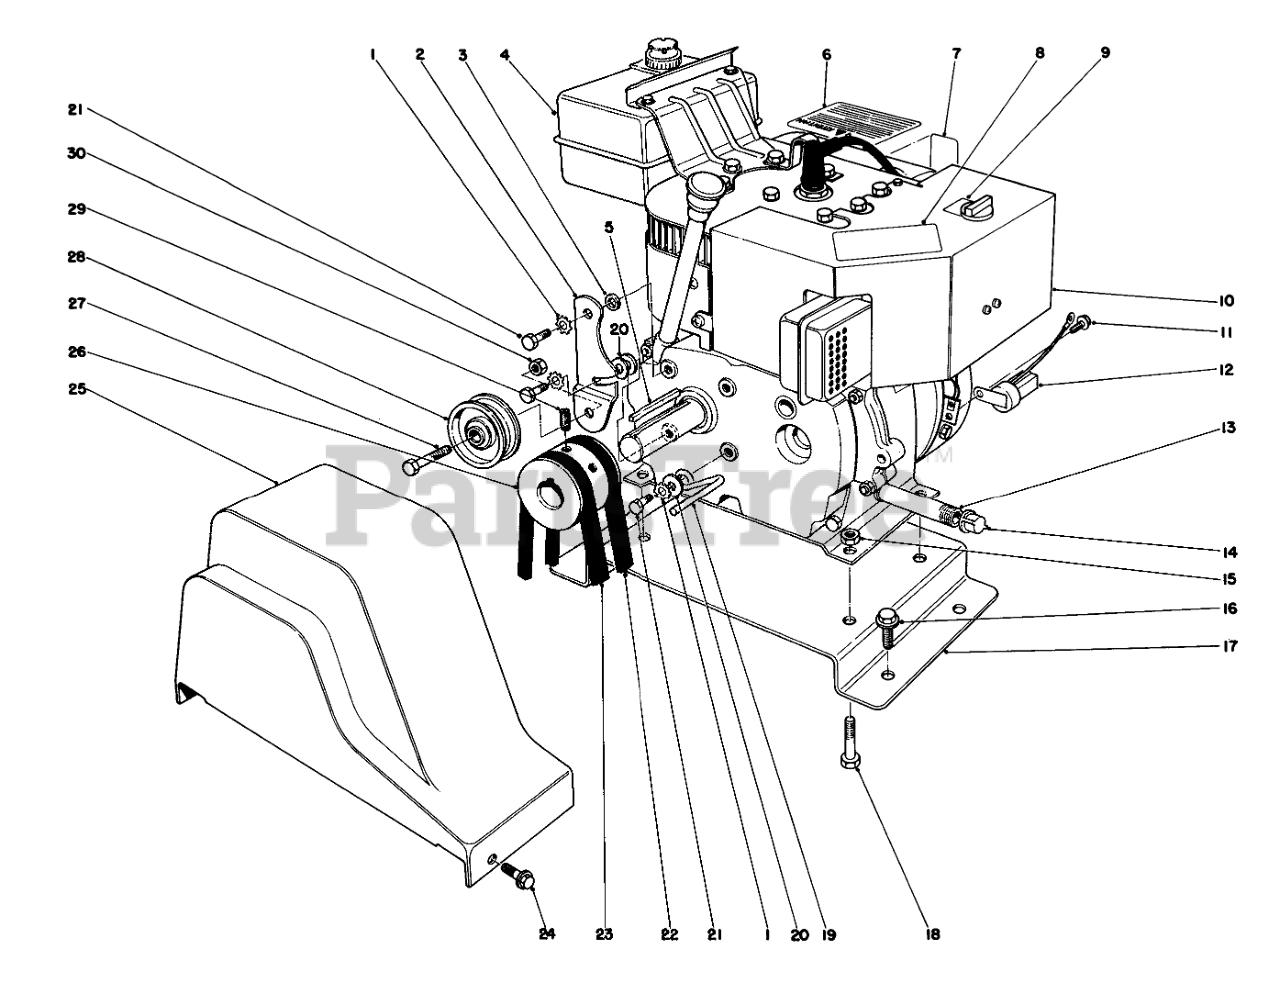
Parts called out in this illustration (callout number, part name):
1	WASHER-LOCK
2	ENGINE IDLER ARM
3	SPACER
4	GAS TANK 2 QT W CAP
6	CAUTION DECAL
7	PRIMER DECAL
8	HOT SURFACE DECAL
9	CHOKE DECAL
10	Engine (Model 38040)
11	SCREW-HWH
12	INTERLOCK MODULE
13	NIPPLE-PIPE
14	CAP-PIPE
15	NUT-LOCK, NI
16	SCREW-HWHTF
17	ENG MTG PLATE R
18	SCREW-HH
19	BELT RETAINER
20	WASHER-PLAIN
21	SCREW-HH
22	V-BELT
23	V-BELT
24	SCREW-HWH
25	BELT GUARD
26	ENGINE PULLEY
27	SCREW-HH
28	PULLEY-IDLER
29	SETSCREW
30	NUT-LOCK, NI
